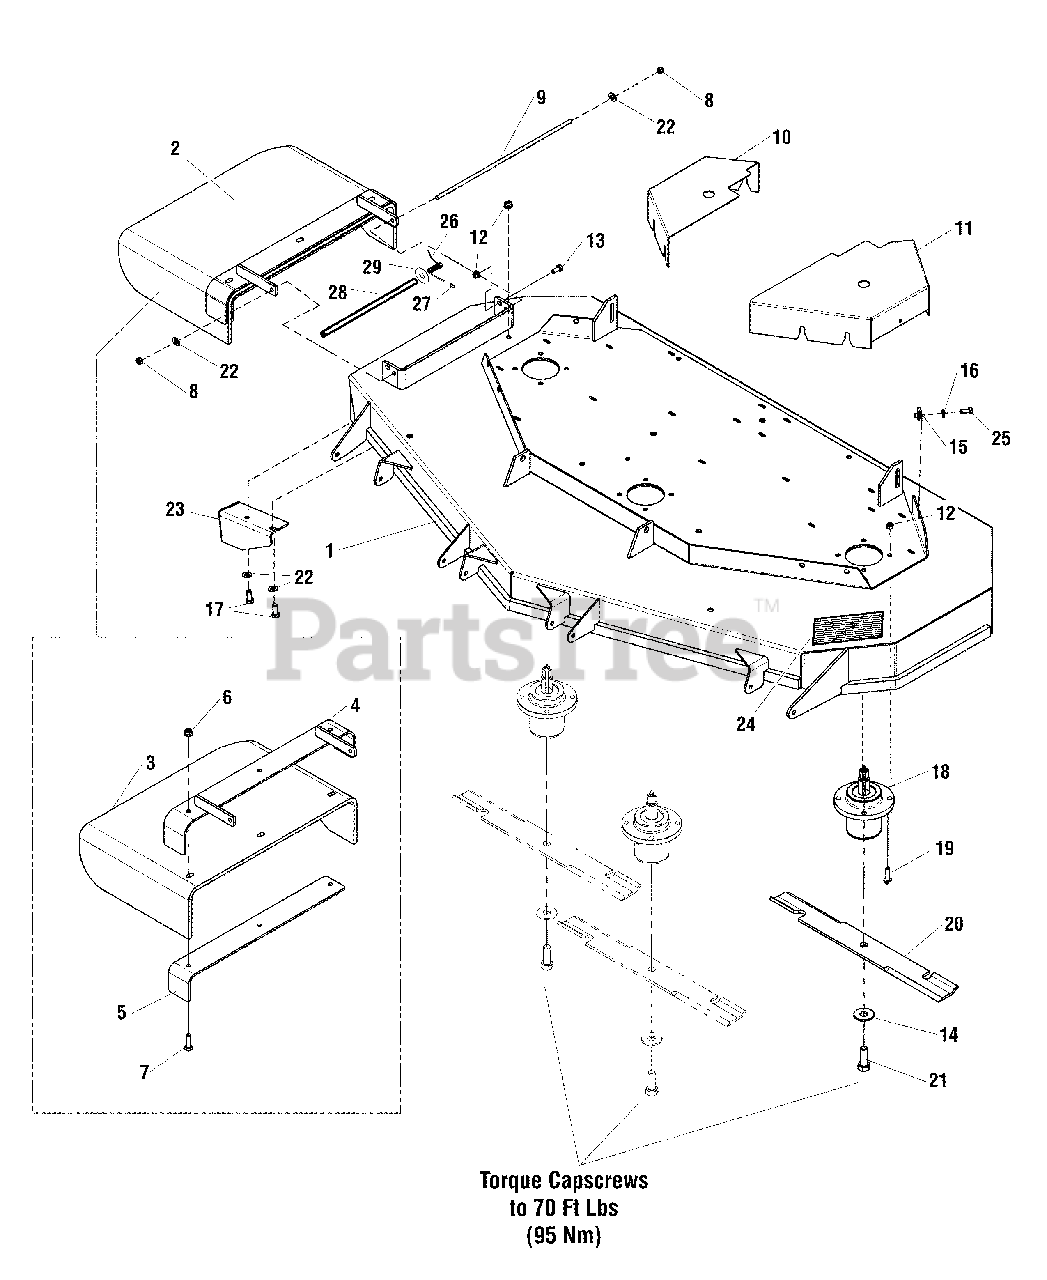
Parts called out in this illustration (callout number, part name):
1	DECK SHELL W/DECALS, 61" SIDE DISCHARGE
2	CHUTE ASSEMBLY, 61"
3	CHUTE, DISCHARGE, RUBBER, 61/72"
4	WELD, FRAME, CHUTE, 61 - ORG
5	SUPPORT, DISCHARGE CHUTE - BLK
6	NUT, 3/8-16 HEX NYLOCK FLANGE
7	BOLT, 3/8-16 X 1-1/2 GD5 YZ
8	NUT, 5/16-24 HEX NYLON LOCK
9	ROD MOUNT, CHUTE 61"
10	GUARD, 61", RH - ORG
11	GUARD 61" - LH
12	NUT, 5/16-18 HEX NYLOCK FLANGE
13	SCREW-HEX WZ LOCK FLNG 5/16-18X0.750BLK
14	WASHER, 5/8 USS
15	CLIP, BODY , 5/16-18 FOR 7 GA.
16	WASHER, 5/16 GD.9 FLAT
17	BOLT, 5/16-18 X 3/4 GD5
18	ASSM, SPINDLE, LOW PROFILE
19	BOLT, 5/16-18 X 1 1/4 FLANGE
20	BLADE SET, 61 DECK (SET OF 3 BLADES)
21	BOLT, 5/8-11 X 1-3/4" GD8
22	WASHER, 5/16 SAE
23	PLATE, DEFLECTOR - BLK
24	SAFETY WALK, 9.75 X 6.00
25	BOLT, 5/16-18 X 1 GD5 YZ
26	SPRING, TORSION
27	CAP, PROTECTOR, .120 ID
28	TUBE, 1/2 X 3/8 BLACK POLY, 10.75 LG
29	WASHER, 5/16 FENDER
